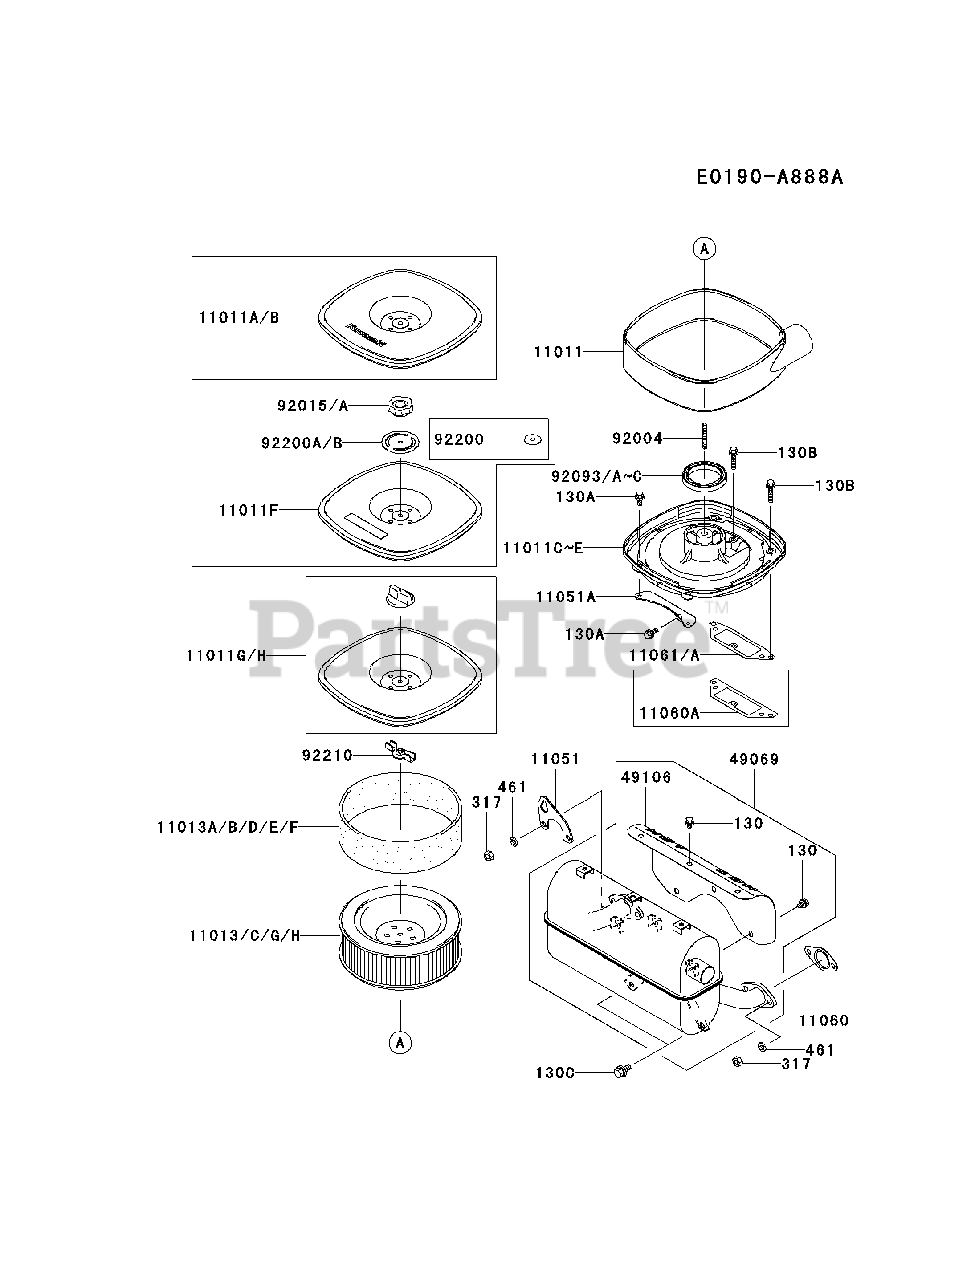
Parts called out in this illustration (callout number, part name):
130C	BOLT-FLANGED,8X16
317	NUT-HEX-SMALL,8MM
461	WASHER-SPRING,8MM
